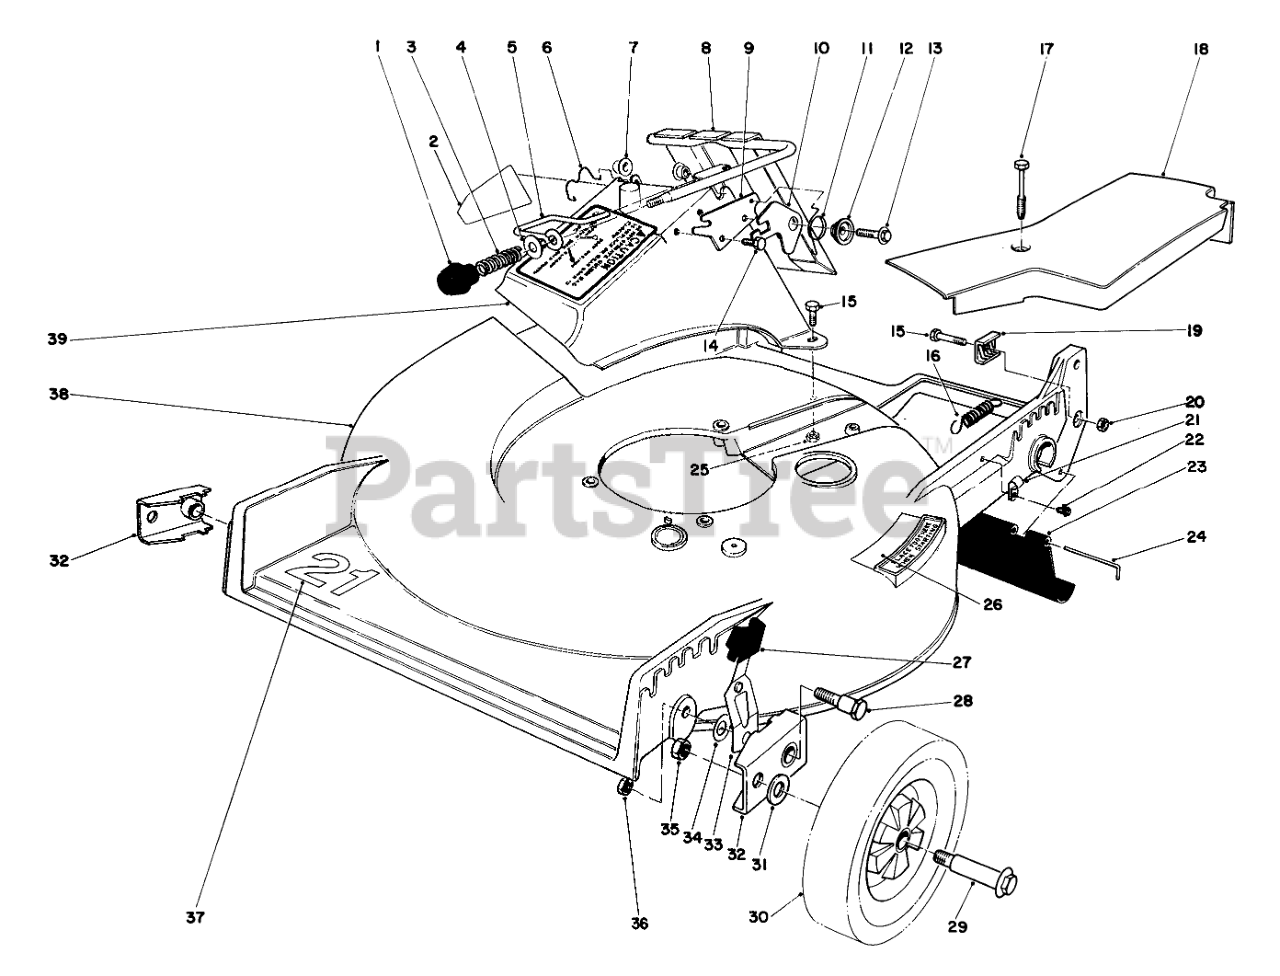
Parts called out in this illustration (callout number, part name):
2	Decal-Attention
3	COMPRESSION SPRING
4	WASHER-FLAT
5	DOOR LATCH
6	DOOR RETAINER
7	BUSHING-NYLON
8	DOOR & HANDLE WA
9	DOOR LATCH PLATE
10	SAFETY LATCH
11	TORSION SPRING
12	DOOR SPACER
13	Screw
14	SCREW-HWH
15	SCREW-HH
16	IDLER SPRING
17	SCREW-HHFTF
18	Belt Cover
19	CLAMP-CABLE
20	NUT-JAM
21	CLAMP-NYLON
22	SCREW-HWH
23	SHIELD - TRAILING
24	Rod Shield
25	NUT-LOCK, NI
26	Decal-Place Foot Here
27	KNOB-ARM
28	PIVOT SCREW
29	BOLT-WHEEL
30	WHEEL TIRE ASM 8 IN
31	WASHER
32	Pivot Arm
33	Spring Arm
34	WASHER-PIVOT
35	Nut
36	Nut
37	Decal 21"
38	Housing
39	DISCHARGE CHUTE B
